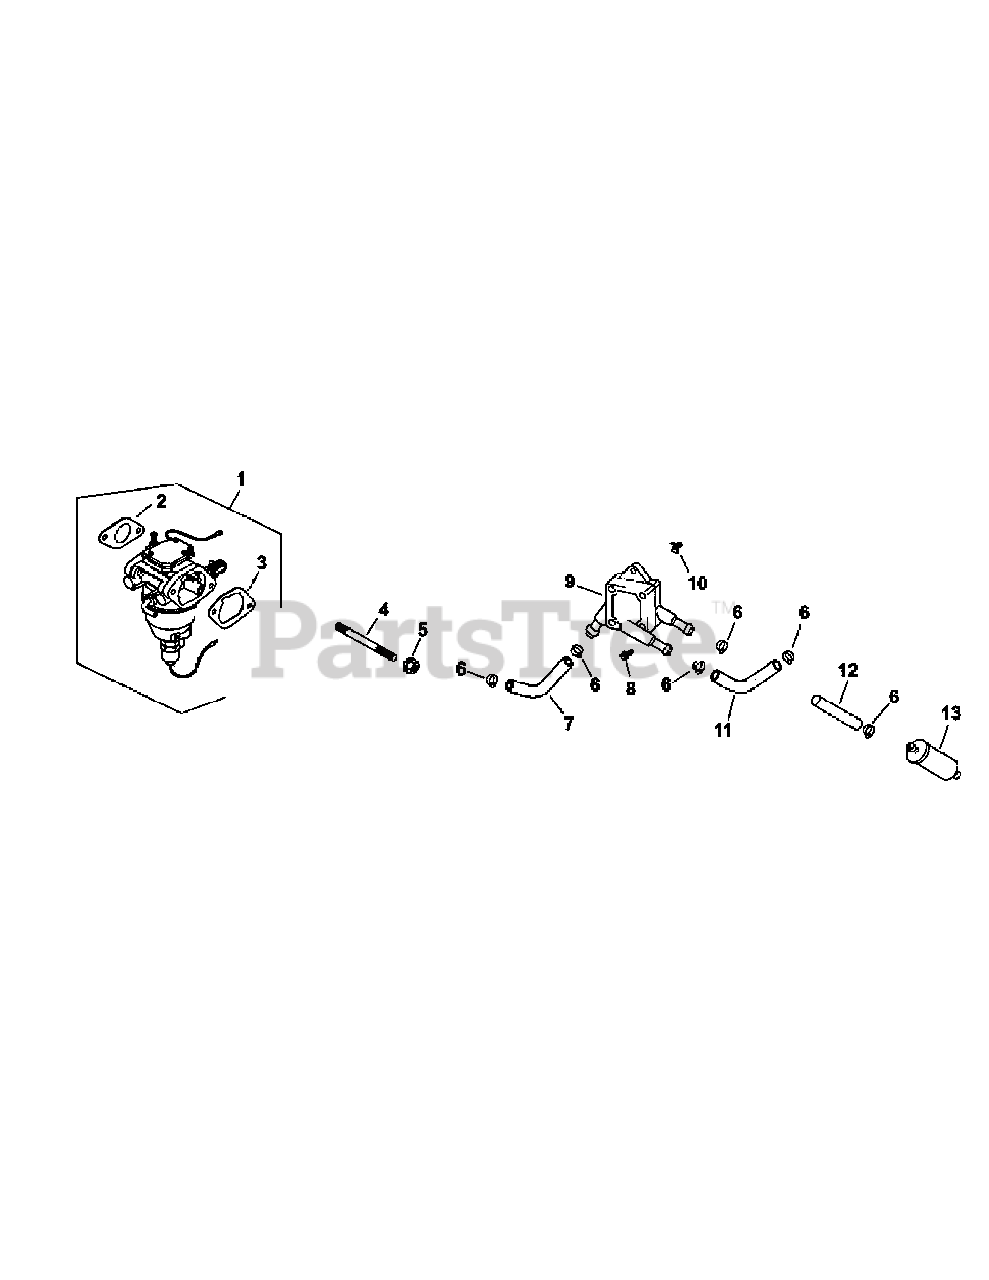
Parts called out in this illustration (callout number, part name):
1	Carburetor w/Gaskets
2	Carburetor Gasket
3	Air Cleaner Base Gasket
4	Intake Manifold Stud
5	Hex Flange Nut (M6 x 1.0)
7	Fuel Line (3-1/2")
8	Hex Cap Screw (M6 x 1.7 x 18)
11	Fuel Line (10-1/2")
12	Fuel Line (3-1/2")
13	Fuel Filter
